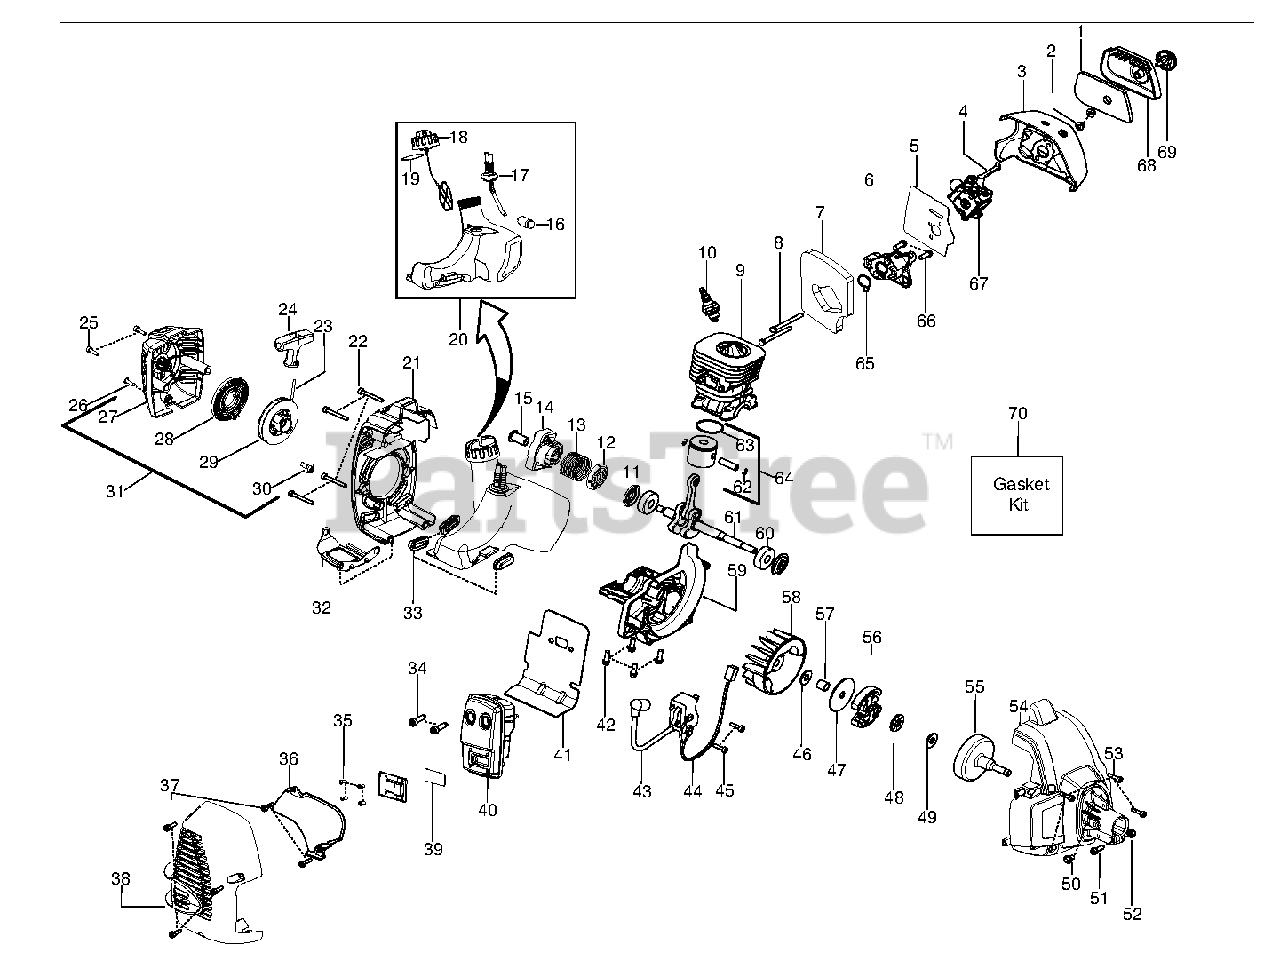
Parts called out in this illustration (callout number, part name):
1	FILTER AIRBOX
4	CHOKE LEVER
5	KIT GASKET CARB
6	CARB ADAPTOR
7	KIT GASKET 28CC
8	BOLT CARB ADAPTOR
9	CYLINDER
11	KIT SEAL CRANKSHAFT
12	WASHER STARTER
13	SPRING STARTER CUP
14	ASSY STARTER CUP
15	COUPLING STARTER
16	FUEL PICK-UP ASSY
17	KIT FUEL LINE
18	ASSY - FUEL CAP W/RETAINER
19	KIT GASKET 28CC
20	FUEL TANK ASSY
21	SHROUD REAR
25	SCREW M5-0.8X30MM
26	SCREW M4 X 1.75 PT 16MM
28	%KIT STARTER SPRING
29	KIT STARTER PULLEY
32	PLATE WEAR
33	ISOLATOR FUEL TANK
34	BOLT MUFFLER
35	SCREW-10-16 X 1/2 HI-LO
36	SHIELD HEAT
37	SCREW M4 X 1.75 PT 16MM
39	KIT SPARK ARRESTOR SCREEN
40	ASSY-MUFFLER
41	KIT GASKET 28CC
42	B0LT, C/SHAFT 36/41
43	IGNITION MODULE
44	ASSY MODULE LEAD WIRE
45	SCREW M4 X .70 TT 16MM
46	WASHER CLUTCH
47	WASHER-CLUTCH
48	BEARING THRUST
49	WASHER THRUST
52	NUT HEX LOCK 10-24
53	SCREW M4 X .70 TT 16MM
55	ASSY-CLUTCH DRUM
56	%KIT CLUTCH ASSY
57	SPACER FLYWHEEL
59	CRANKCASE CASTING
60	BEARING RADIAL BALL (6201)
61	KIT CRANKSHAFT ASSY
62	WRIST PIN RET.
63	RING PISTON
64	KIT PISTON 28CC TRIMMER
65	KIT GASKET 28CC
66	B0LT, C/SHAFT 36/41
67	KIT CARB
68	COVER AIR BOX
69	ASSY - AIR BOX KNOB
70	KIT GASKET 28CC
